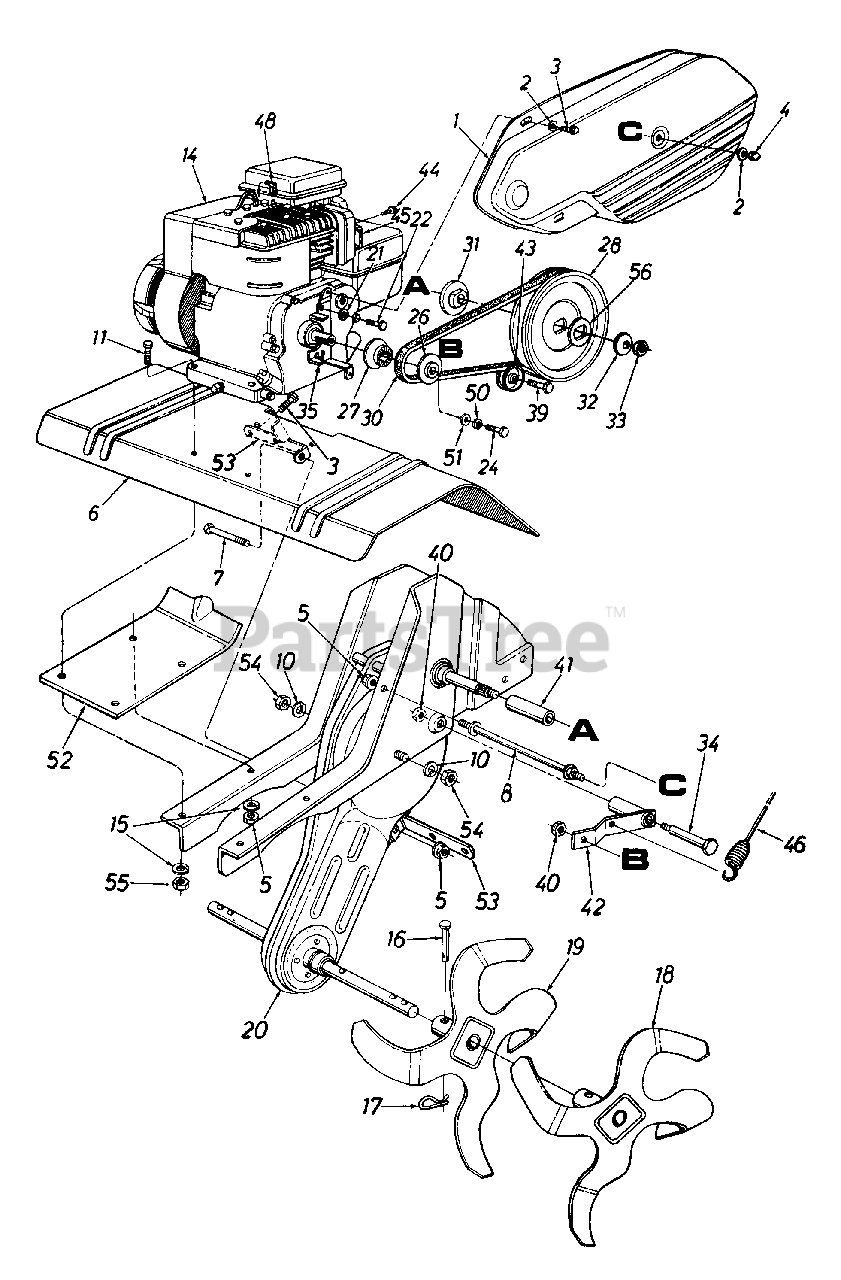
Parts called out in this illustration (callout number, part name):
2	Fl-Wash. .266" I.D. x .625" O.D.
3	Hex Wash. Hd. TT-Tap Scr. 1/4-20 x .5" Lg.
4	Hex L-Stop Nut 1/4-28 Thd.
5	Hex Flange Top L-Nut 5/16-18 Thd. (Gr. 5)
8	Belt Cover Bolt
10	L-Wash. 7/16" I.D.
11	Hex Bolt 5/16-18 x 1.75" Lg.
14	Engine
15	Spec. L-Nut 5/16" I.D.
16	Clevis Pin .375" dia. x 1.75" Lg.
17	Internal Cotter Pin
20	Chain Case Ass'y. Comp.
21	L-Wash. 5/16" I.D.
22	Hex Bolt 5/16-24 x .5" Lg.
24	Hex Bolt 3/8-24 x 1.25" Lg.
26	Outer Engine Pulley Half
27	Inner Engine Pulley Half
28	Fl-Pulley 6" Dia.
30	"V"-Belt
31	Pulley mounting Adapter
32	Bell-Wash. .535" I.D. x 1.5" O.D.
33	Hex Jam Nut 1/2-20 Thd. (Gr. 5)
34	Shld. Bolt .498" Dia. x 1.45" Lg.
39	Hex Cap Bolt 3/8-16 x 1.25" Lg.
40	Hex Cent. Jam Nut 3/8-16 Thd.
41	Spacer .64" I.D. x 2.4" Lg.
42	Tine Idler Brkt. Ass'y.
43	Fl-Idler 2" O.D.
44	Hex Self-Tap Scr. #8-32 x .38" Lg.
45	Muffler Deflector
46	Clutch Control Cable
48	Spark Plug Boot
50	L-Wash. 3/8" I.D.
51	Fl-Wash. 3/8" I.D. x 1" O.D.
54	Hex Nut 7/16-20 Thd.
55	Hex Nut 5/16-18 Thd.
56	Bearing Retainer Washer
